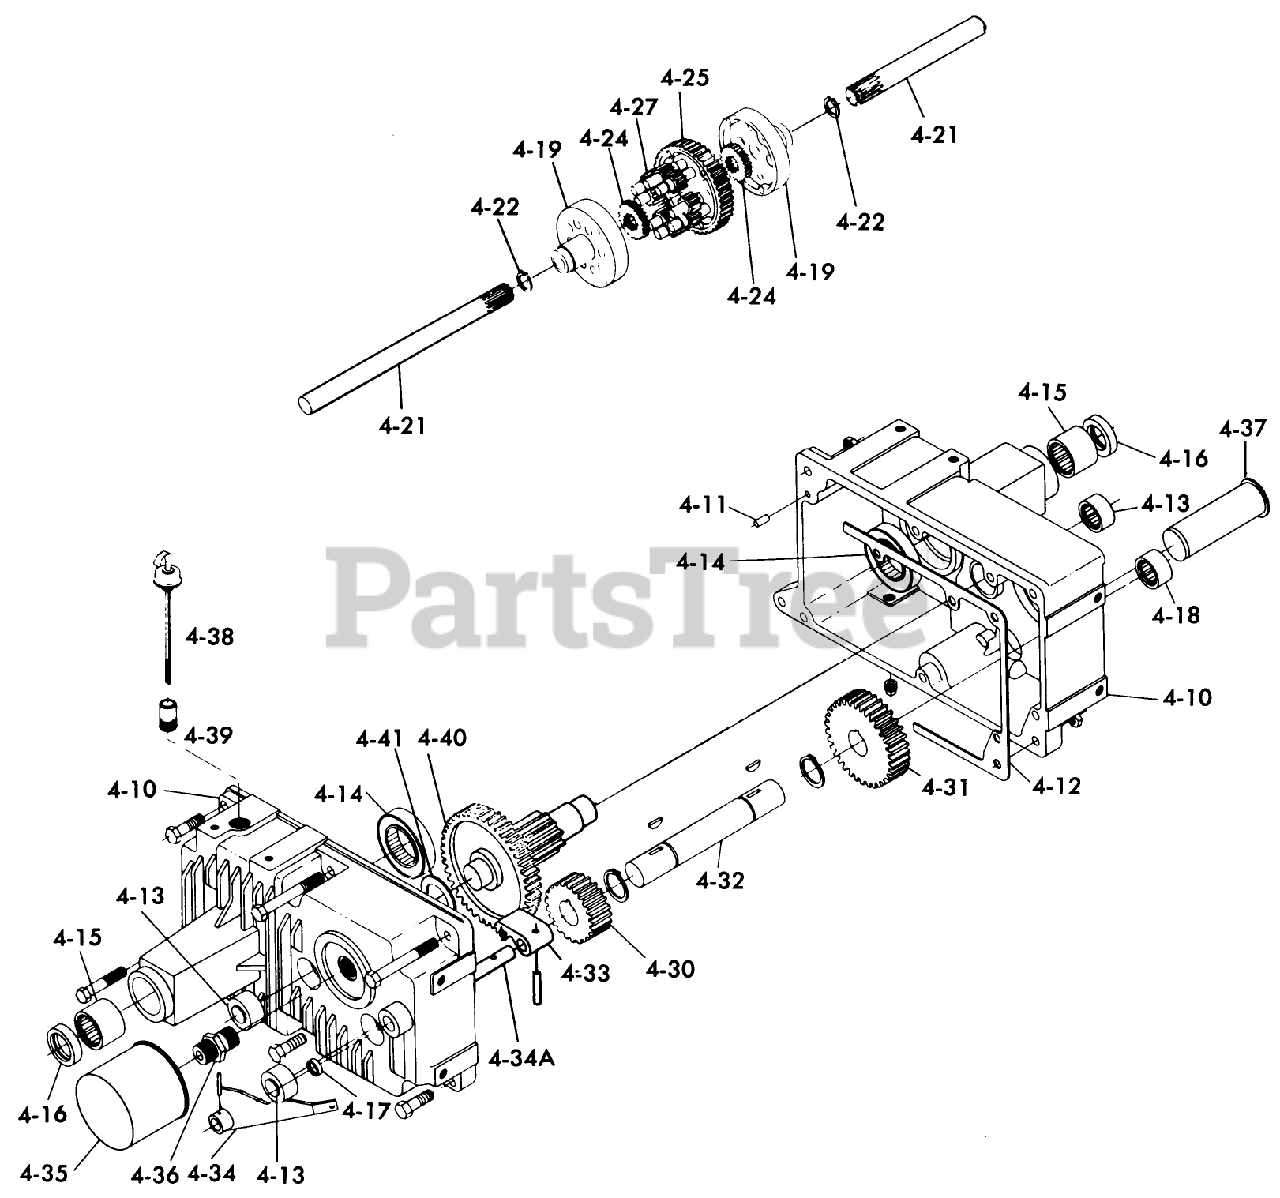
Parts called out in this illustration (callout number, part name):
4-10	RH TRANSMISSION CASE
4-10	Case LH
4-10	PLUG 1/4 PIPE ALLEN
4-10	H H C S
4-10	HHCS
4-10	Bolt
4-10	Washer
4-10	Nut
4-10	BOLT
4-11	PIN-DOWEL
4-12	GASKET
4-13	BEARING-NEEDLE
4-14	BALL BRG 1 1/2 I.D.
4-15	Bearing-Axle
4-16	SEAL-OIL
4-17	SEAL BRAKE SHAFT
4-18	Needle Bearing
4-19	DIFFERENTIAL END CAP
4-19	BOLT-HEX
4-19	NUT
4-21	Axle
4-22	SNAP RING
4-24	GEAR-AXLE DIFFERENTIAL
4-25	GEAR-DIFFERENTIAL RING, 43T
4-27	GEAR-PINION, 11T
4-30	GEAR 24T
4-31	Gear 44T
4-32	SHAFT GEAR
4-32	Snap Ring
4-32	Key
4-33	PAWL PARKING
4-34	Brake Lever
4-34A	Shaft
4-34A	Pin-Roll
4-34A	PIN-ROLL
4-35	Filter
4-36	FITTING
4-37	Strainer
4-38	Dipstick
4-39	Nipple
4-40	GEAR ASSY
4-40	PINION SHAFT
4-40	Gear-42T
4-41	WASHER-THRUST
